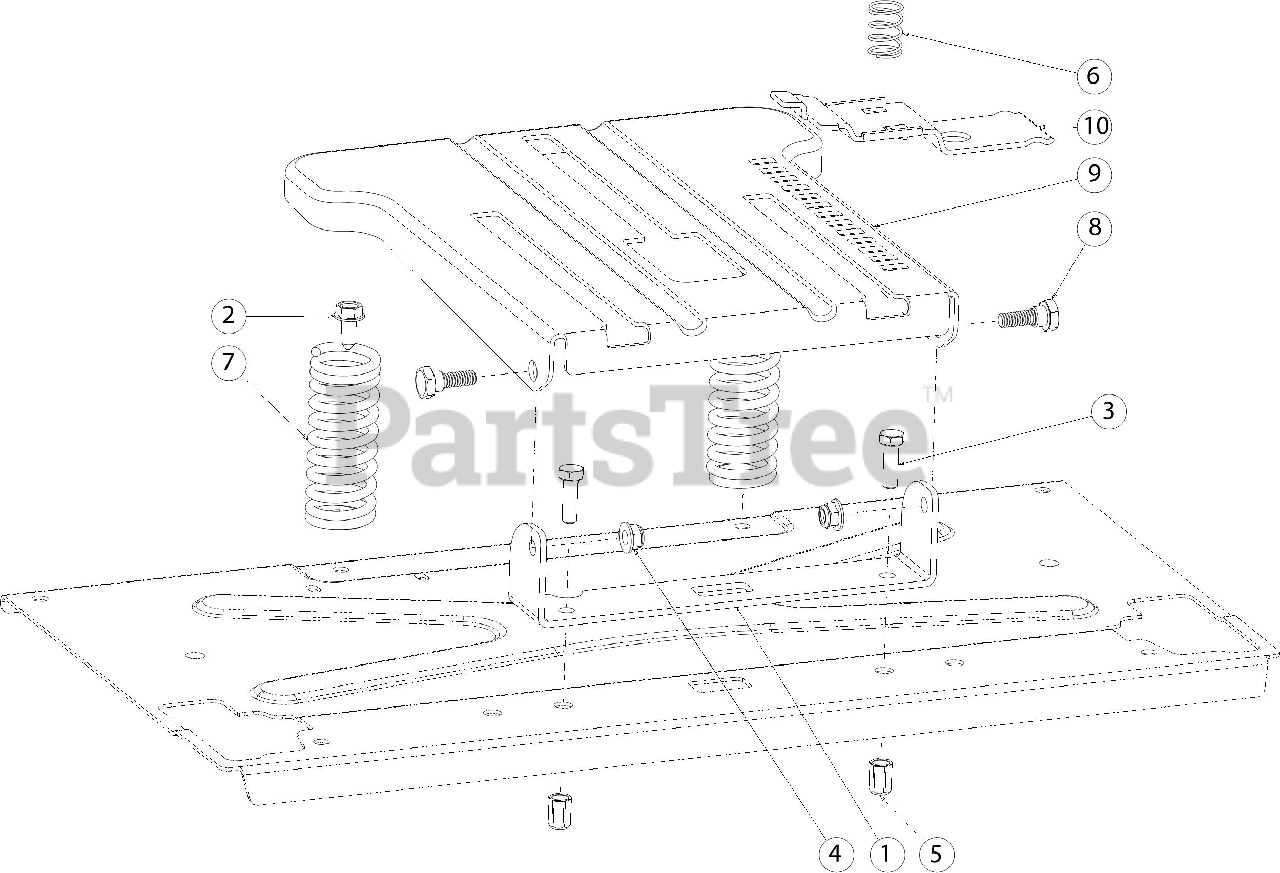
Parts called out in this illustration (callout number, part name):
1	SEAT PIVOT BRACKET
2	SCREW 5/16-18 X .750
3	SCREW 5/16-18 X 1.00 GR5
4	FLANGE LOCK NUT 5/16-18
5	NUT RIVET 5/16-18
6	COMPRESSION SPRING
7	COMPRESSION SPRING
8	SHOULDER SCREW .437
9	SEAT MOUNTING BRACKET
10	SEAT ADJUST LEVER
